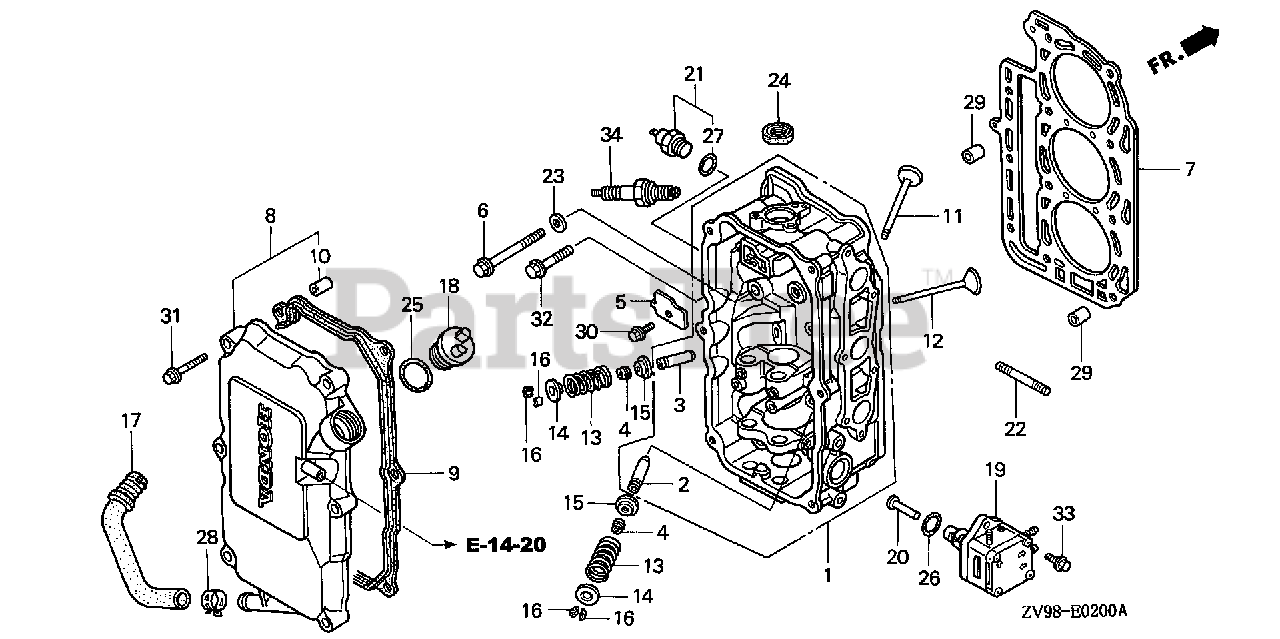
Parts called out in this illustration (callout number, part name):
1	CYLINDER HEAD *NH8* (DARK GRAY)
2	GUIDE, VALVE (OVER SIZE)
3	GUIDE, EX. VALVE (OVER SIZE)
4	SEAL, VALVE STEM (NOK)
5	PLATE, OIL CHAMBER
6	BOLT, FLANGE (8X80)
7	GASKET, CYLINDER HEAD
8	COVER, CYLINDER HEAD
9	GASKET, HEAD COVER
10	COLLAR, HEAD COVER
11	VALVE, IN.
12	VALVE, EX.
13	SPRING, VALVE
14	RETAINER, VALVE SPRING
15	SEAT, VALVE SPRING
16	COTTER, VALVE (SANKO)
17	TUBE SET, OIL
19	PUMP ASSY., FUEL
19	PUMP ASSY., FUEL (MSDS)
20	LIFTER, FUEL PUMP
21	SWITCH ASSY., THERMOSTAT
22	BOLT, STUD (6X28)
23	WASHER, PLAIN (8MM)
24	OIL SEAL (20X32X6)
25	O-RING (26X2.7)
26	O-RING (20.8X2.4)
27	O-RING (13.5X1.4)
28	CLAMP, TUBE (D17)
29	PIN, DOWEL (10X12)
30	BOLT, FLANGE (6X12)
31	BOLT, FLANGE (6X35)
32	BOLT, FLANGE (8X40)
33	BOLT, FLANGE (6X20)
33	BOLT, FLANGE (6X20) (SH)
34	SPARK PLUG (DR7EA) (NGK)
34	SPARK PLUG (X22ESR-U) (DENSO)
